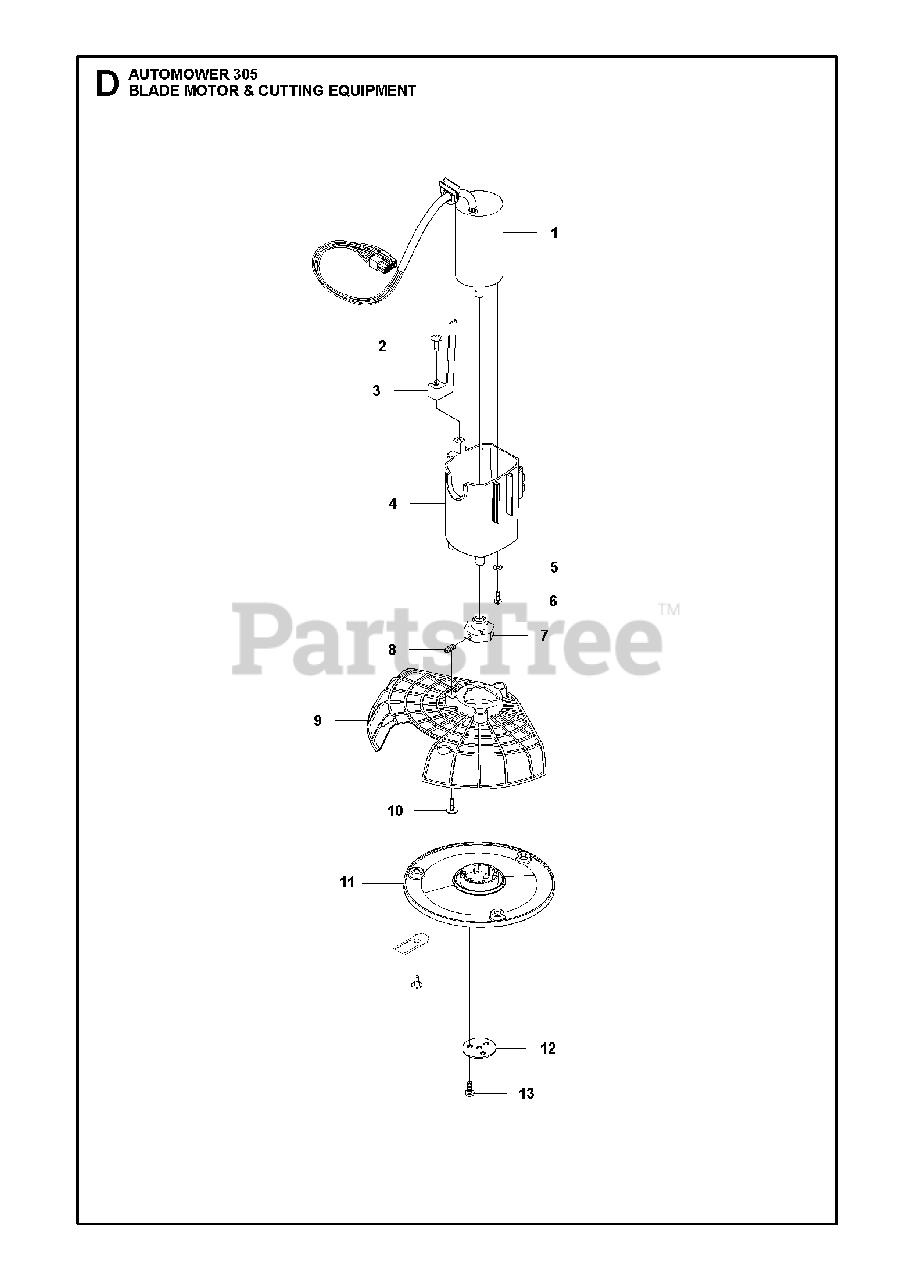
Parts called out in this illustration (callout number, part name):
2	SCREW 14MM
3	HEIGHT INDICATOR
7	HUB CUTTING MOTOR
8	SCREW IHSETM M5X10 8.
10	SCREW 14MM
11	Cutting Disc
12	WASHER DRIVE WHEEL
13	SCREW ITXPANM M4X12 8
